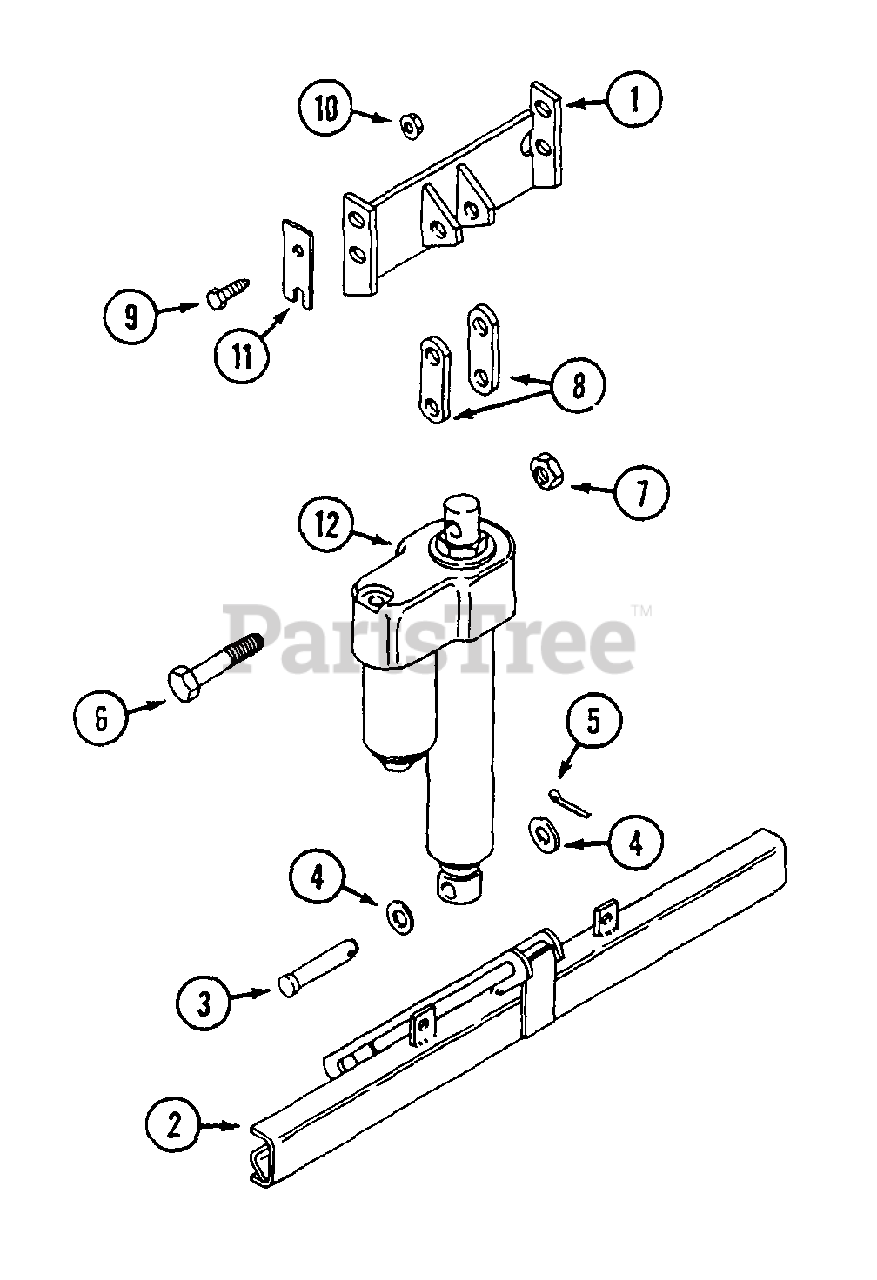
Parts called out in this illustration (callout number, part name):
1	MOUNT - cylinder
3	PIN - clevis 1/2" x 2-1/2"
4	WASHER - 1/2"
5	PIN - cotter 5/32" x 1"
6	BOLT - 1/2" - 13 x 2-3/4"
7	NUT - 1/2" - 13 lock
8	LINK - spacer
9	BOLT - 5/16" - 18 x 1"
10	NUT - 5/16" - 18 flange lock
11	SHIM - cylinder mount
12	CYLINDER - lift
